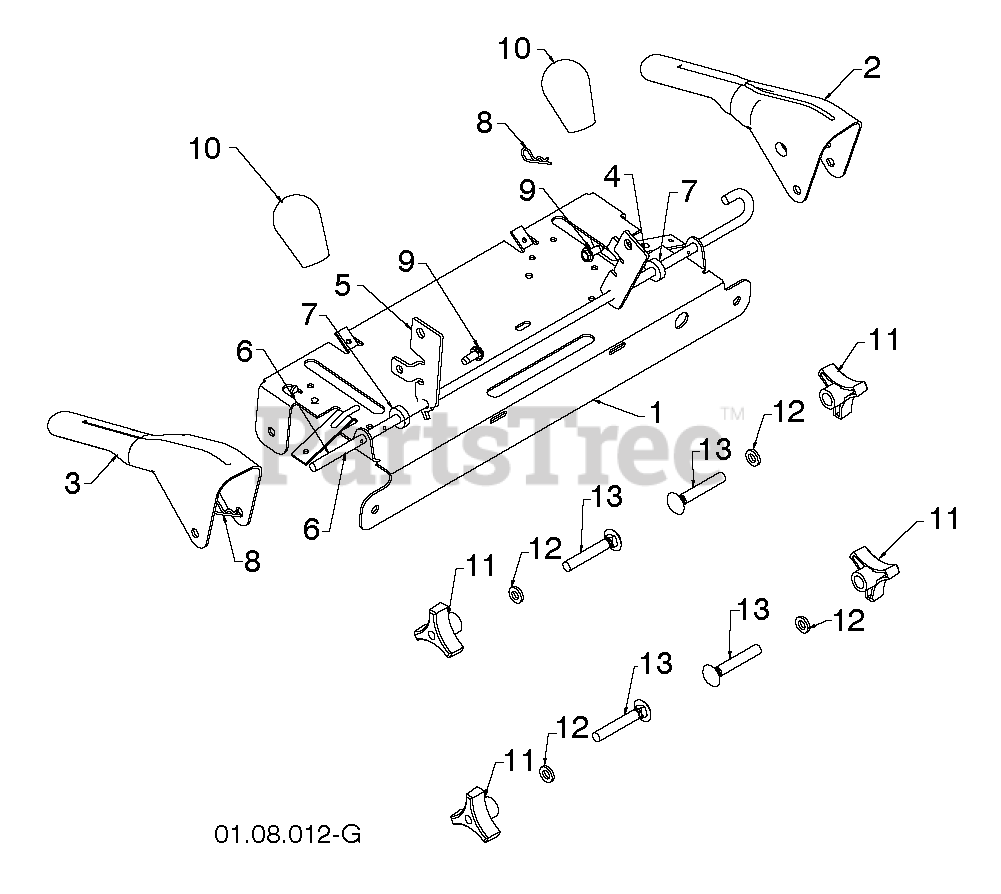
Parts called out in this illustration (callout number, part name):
1	PANEL.CONTROL.SNOW.BLACK
2	LEVER.CONTROL.LH.BLACK
3	LEVER.CONTROL.RH.GREY
4	TRACTION ROD ARM
5	ARM.IMPELLER.ROD.
6	BAIL.CONTROL.INTERLOCK
7	SPACER.CONTROL.LEVER
8	SPRING RETAINER
9	SCREW 14-20 X 5/8
10	KNOB.OVERMOLD.DS.HUSQVARNA/BLK
11	KNOB.HANDLE.3/8.TRI-POINT.BLAC
12	WASHER
13	BOLT 3/8-16 X 2-1/4
